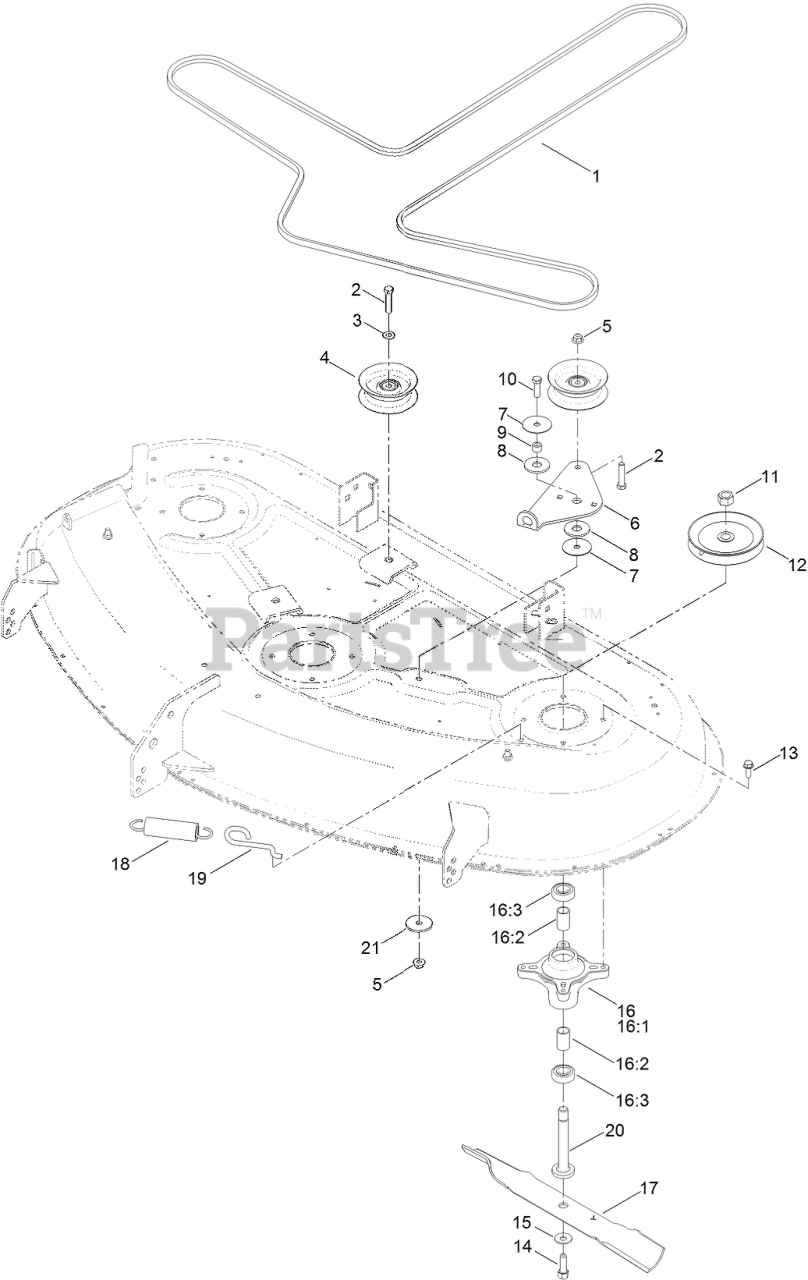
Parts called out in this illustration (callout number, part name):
1	BELT-V
2	SCREW-HH
3	WASHER-FLAT
4	PULLEY-IDLER, FLAT
5	NUT-HF, NI
6	ARM-IDLER
7	WASHER
8	WASHER-FRICTION, COMPOSITE
9	SPACER
10	SCREW-HH
11	NUT-HEX
12	PULLEY ASM
13	SCREW-TAPTITE
14	SCREW-HH
15	WASHER-BELLEVILLE
16	SPINDLE ASM
16:1	SPINDLE
16:2	SPACER
16:3	BEARING-BALL
17	BLADE-HI LIFT, 18.75 INCH
18	SPRING-EXTENSION
19	HOOK-RETURN, SPRING
20	SHAFT-SPINDLE
21	WASHER-REBOUND
